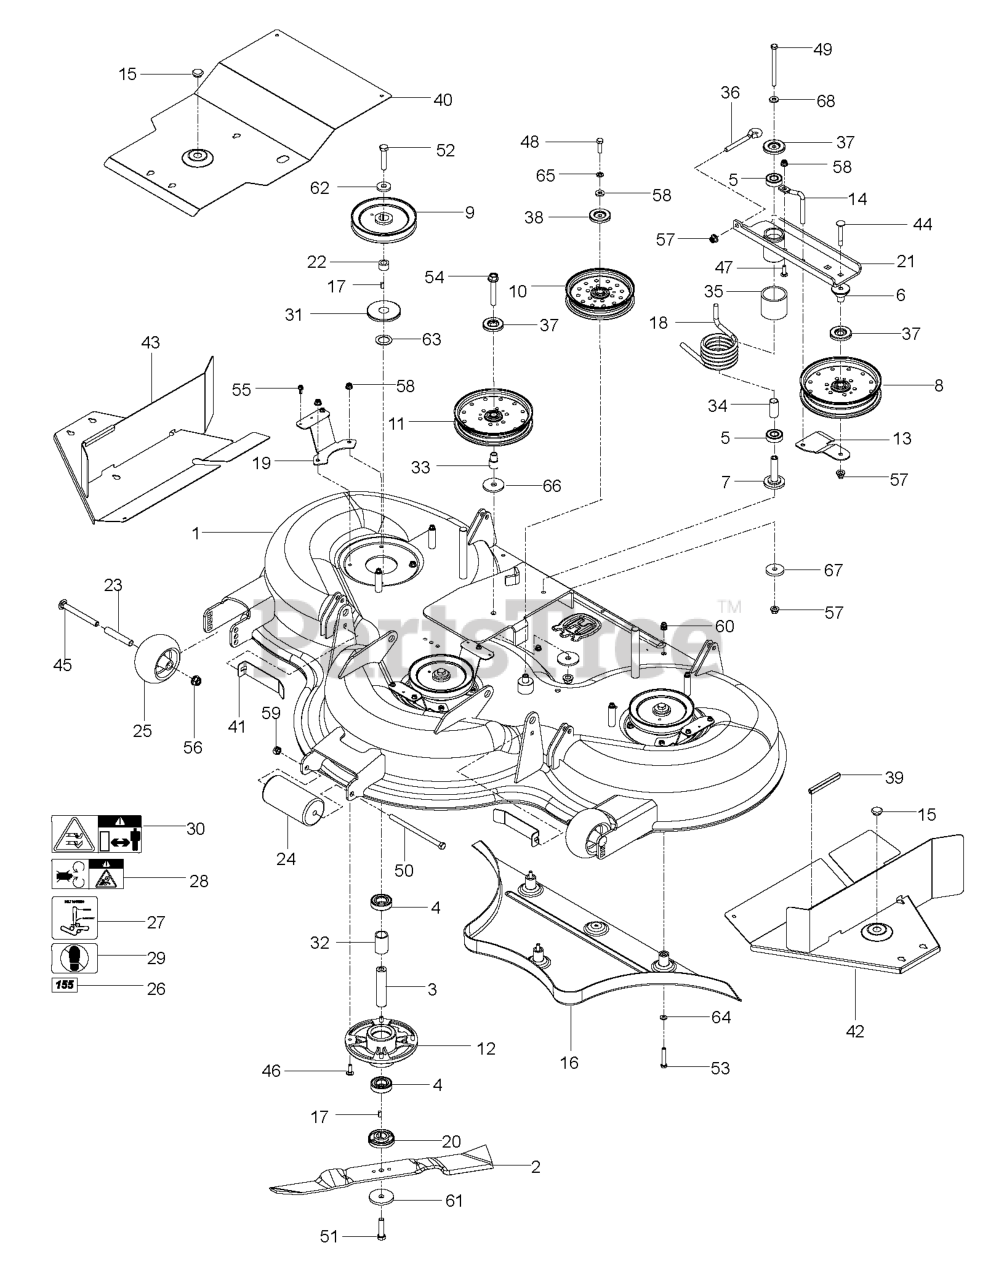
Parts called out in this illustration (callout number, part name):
1	DECK W/SAFETY DECALS
4	BALL BEARING
5	BEARING, BALL
6	BEARING, IDLER ARM
7	BEARING, IDLER PIVOT
8	PULLEY - IDLER 7"
9	PULLEY, 61
10	PULLEY IDLER, 6" NARROW
11	PULLEY - 7" NARROW
12	BEARING HOUSING
13	BELT.GUIDE.BLACK
14	BELT KEEPER
15	PLUG, BUTTON HOLE
16	PLUG ASSEMBLY
18	SPRING, TORSION, IDLER
19	BRACKET,BELT CVR,COMBI BLK
20	BUSHING, BLADE
21	IDLER.ARM.BLACK
22	KEY RETAINER
23	TUBE, ROLLER AXLE
24	ROLLER
25	ROLLER, GAUGE .635 BORN
26	DECAL, 155
27	DECAL, BELT ROUTING
28	DECAL, BELT DRIVE
29	DECAL, NO STEP
30	DECAL, EURO SEVERING
31	TOP DUST CAP
33	SPACER - IDLER
34	SPACER, IDLER BEARINGS
35	SPACER, IDLER PIVOT
36	EYE BOLT, 3/8 X 4"
37	DUST SHIELD
38	SHIELD, DUST
39	RP.FLEX TRIM, BLK-LENGTH 1 FT
40	GUARD.CENTER.COMBI.61.BLACK
41	GUARD, COMBI STRUT, BLK
42	WLDMNT, LEFT COMBI 61, BLK
43	WLDMNT, RIGHT COMBI 61, BLK
44	CARRIAGE BOLT 3/8-16 X
45	RHSNB 1/2-13 X 4.75 GR5 ZD
46	RHSNB 5/16C X 1
47	RHSSNB 5/16C X 1.0
48	HCS 3/8C X 1 1/4 GR5
49	HCS 3/8F X SPECIAL
50	HCS 7/16-14 X 7 GR5 ZD
51	HCS M12 X 1.75 X 50 GR8.8 ZD
52	HCS M12 X 1.75 X 60 GR5 ZD
53	HCS M8 X 1.25 X 50 GR8.8 ZD
54	HFFS 1/2-13 X 3 GD 5 ZD
55	SCREW- 1/4-20 X 5/8
56	NUT, 1/2-13 HEX FLG NYLOC ZD
57	NUT 3/8-16 HEX FLG NYLOC ZD
58	5/16-18 NYLOC FLANGE NUT
59	NUT 7/16C CENTERLOCK
60	BLIND RIVET NUT
62	WASHER-.533IDX1.37OD
63	WASHER-1.06IDX1.63ODX.06
64	FLAT WASHER 5/16 SAE
65	SLW 3/8 STD
66	WASHER, HEAVY
67	SPINDLE WASHER
68	WASHER, 3/8 THICK
